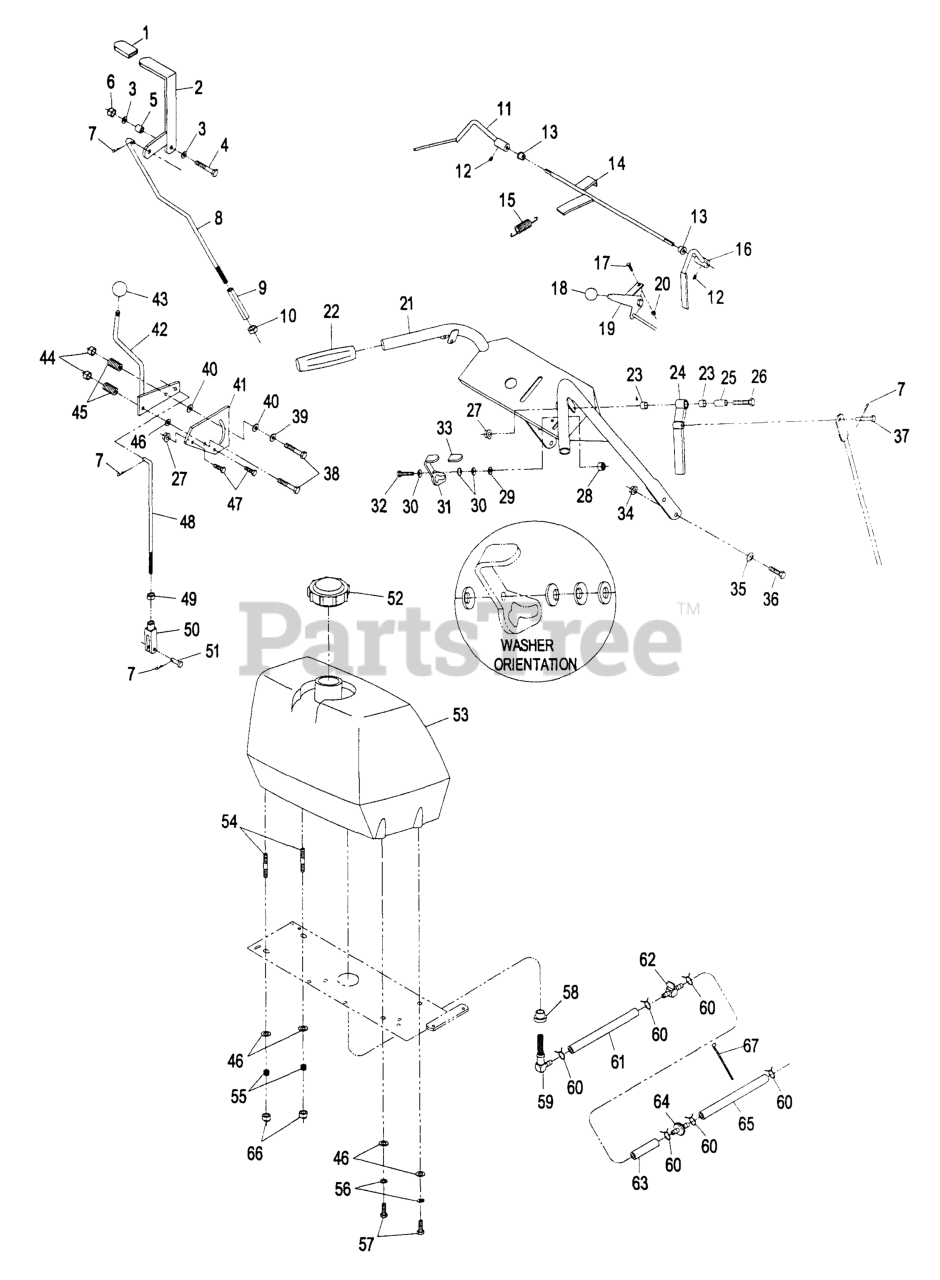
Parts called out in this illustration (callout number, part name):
1	GRIP-LEVER
5	BUSHING-LEVER, LIFT
7	PIN-COTTER
8	LINKAGE,UPPER
9	TURNBUCKLE
11	LEVER-LH
12	SCREW-SET
13	BUSHING-NYLON
14	WLD,ROD OPC
15	SPRING-EXTENSION
16	LEVER-RH
17	BOLT-CARR
18	KNOB-BALL
19	CABLE,THROTTLE CONTROL
23	BUSHING-SLEEVE
25	BUSHING-LEVER, DRIVE
30	WASHER-SPRING
33	GRIP-LATCH
35	WASHER-BELLEVILLE
37	PIN-CLEVIS
39	WASHER-FRICTION
40	WASHER-FRICTION
41	PLATE-LEVER, SHIFTER
43	KNOB-BALL
45	SPRING-COMPRESSION
48	ROD,SPEED CONTROL
50	YOKE-ADJUSTABLE
51	PIN-CLEVIS
52	CAP-FUEL
54	STUD
55	SPRING-TANK, FUEL
56	WASHER-LOCK
59	ELBOW-TANK, FUEL
60	CLAMP
61	HOSE-FUEL
62	VALVE-FUEL
63	HOSE-LINE, FUEL
65	HOSE-LINE, FUEL
67	TIE-PLASTIC
